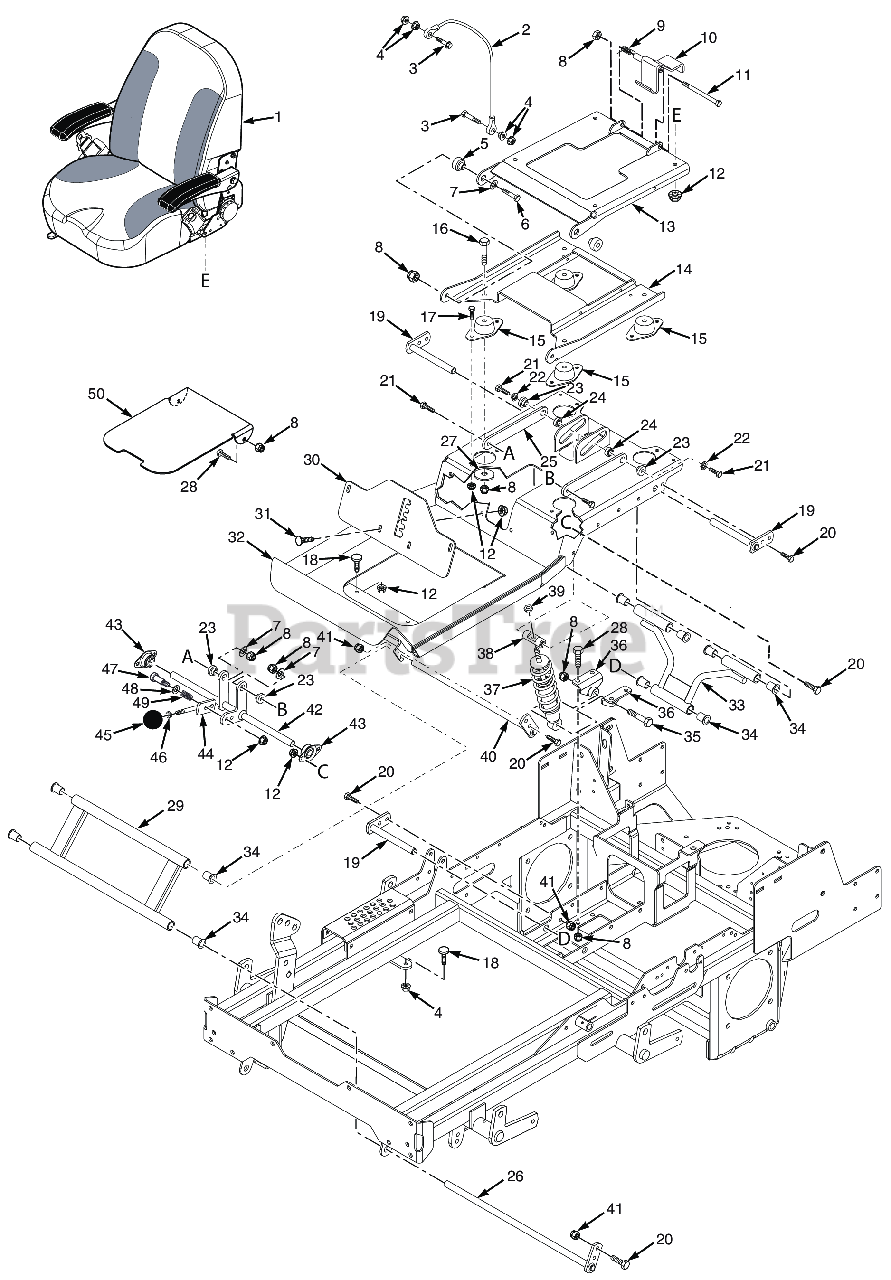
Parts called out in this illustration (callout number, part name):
1	Seat Assembly - SCZ
2	Cable, Seat Stop
3	SERR. FLG. HEX HEAD CAPSCREW, 5/16-18 X 3/4
4	NUT, 1/4-20 SERRATED FLANGE HEX HEAD
5	Sleeve, Seat Base Mounting
6	Capscrew, Hex Head 3/8-16 x 2.0"
7	Flatwasher, 3/8" Special (.391 x .938 x .105)
8	HEX NUT, ELASTIC STOP LOCK, 3/8-16
9	Spring, Seat Latch
10	Latch Weldment, Seat
11	Bolt, 3/8-16 x 6.00" Hex Head
12	Nut, Serrated Flange 5/16-18 (Right Front Engine Mounting, Briggs and Kohler Only)
13	Seat Plate Weldment
14	Seat Mounting Plate Weldment w/Decal
15	Isolator, Seat
16	Bolt, Hex Head 3/8-16 x 2-1/4" - 61"
17	BOLT, SERRATED FLANGE HEX HEAD 5/16-18 X 3/4"
18	Bumper, Rubber
19	Shaft Weldment, Rear Op. Platform Pivot
20	Bolt, Heax Head 5/16-18 x 1" (48V / 52V)
21	Bolt, Hex Head, 3/8-16 x 1-1/2"
22	Lockwasher, 3/8" Spring, Kawasaki FX / FS
23	BUSHING, SPEED ADJUSTMENT LEVER
24	Bearing
25	Link, Suspension Seat Tensioner
26	Pin Weldment, Op Platform Lower Pivot
27	Flatwasher, 3/8-.406 x 2.25" x .1875
28	Bolt, Hex Head, 3/8-16 x 1 Gr. 5
29	Suspension Pivot Assembly, Front
30	Bracket, Suspension Adjustment w/Decal
31	Bolt, Carriage 5/16-18x1" (large frame units only)
32	Seat Mounting Base Weldment w/Decal
33	Suspension Pivot Assembly, Rear
34	Bearing, .625 ID Plastic
35	Capscrew, Hex Head 3/8-16 x 2.75"
36	Mount Weldment, Shock
37	Shock Absorber, Suspension
38	Mount, Suspension Shock
39	Nut, Elastic Stop 3/8-16, grade 8 black
40	Pin Weldment, Op Platform Upper Pivot
41	HEX NUT, ELASTIC STOP LOCK, 5/16-18
42	Pivot Weldment, Suspension Tensioner
43	Bearing, Self Aligning - 5/8 I.D.
44	Adjustment Lever, Suspension
45	Knob, OCDC Lever
46	HEX NUT, JAM 3/8-16
47	Bolt, Shoulder 3/8 x 1"
47	Bolt, Shoulder 3/8 x .375"
48	RING, RETAINING 1.125 DIAMETER EXTERNAL "E"
49	Spring, Speed Control Slide
50	Cover, Foot Plate
